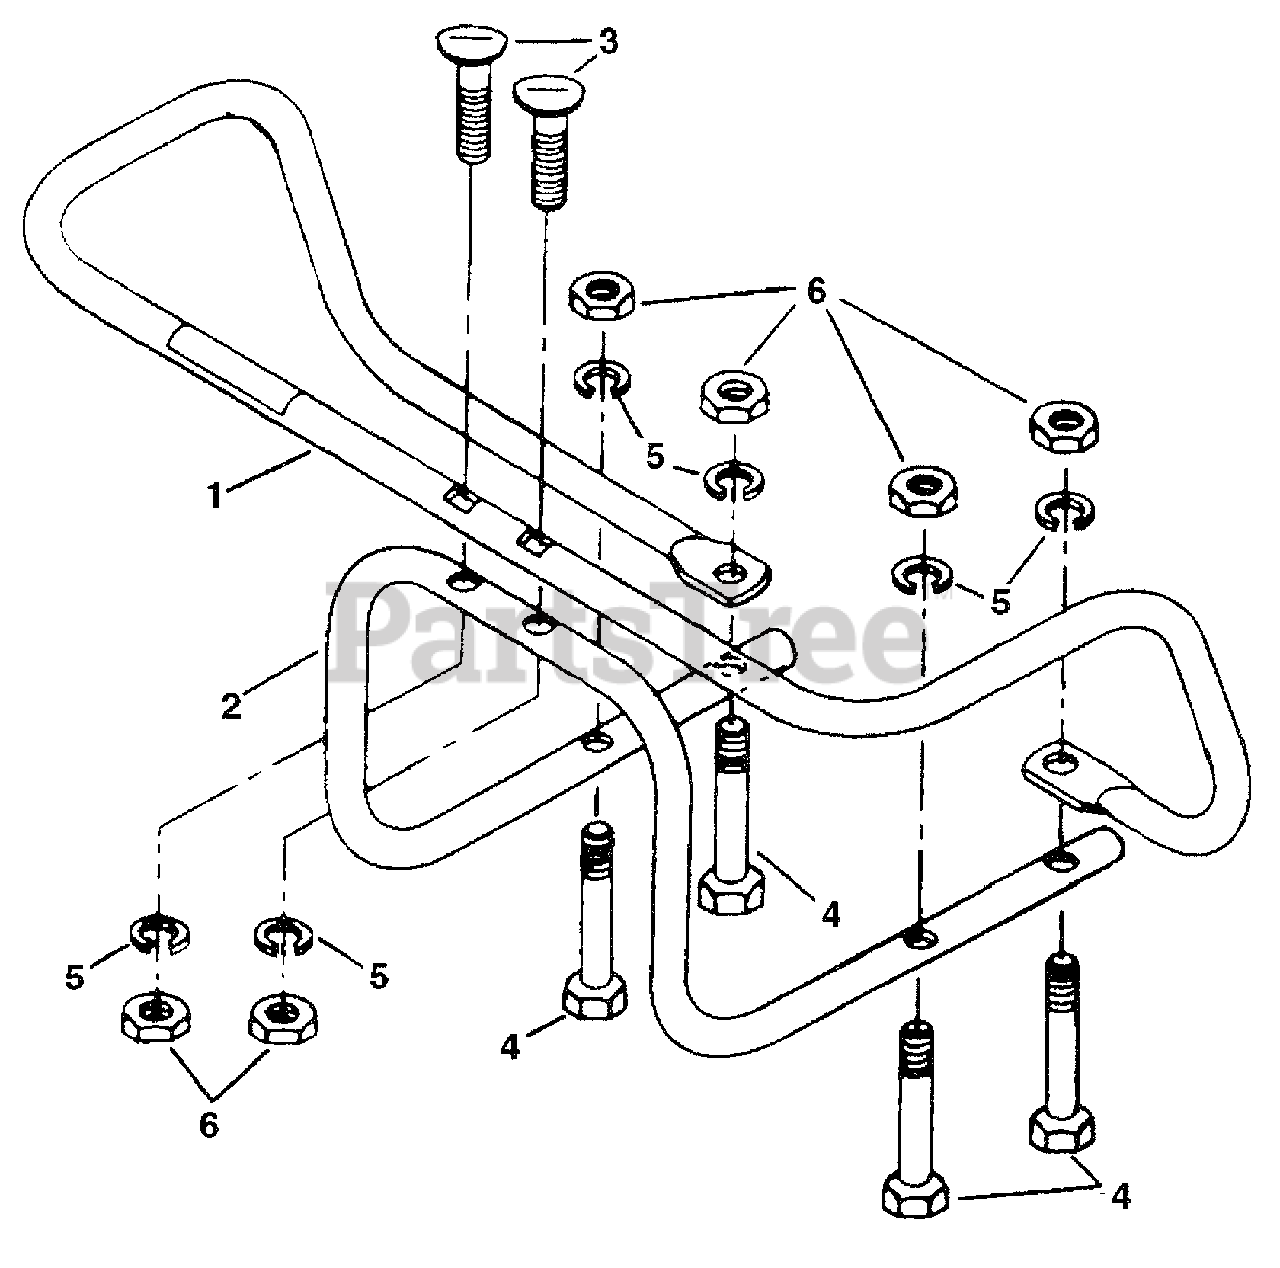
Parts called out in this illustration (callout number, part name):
1	Bumper-top section
2	Bumper-bottom section
3	Bolt-curved head, 5/16-18 x 2 (special bolt);
4	Bolt-hex hd., 5/16-18 x 2-1/2,
5	Lockwasher-5/16,
6	Nut-hex, 5/16-18,
